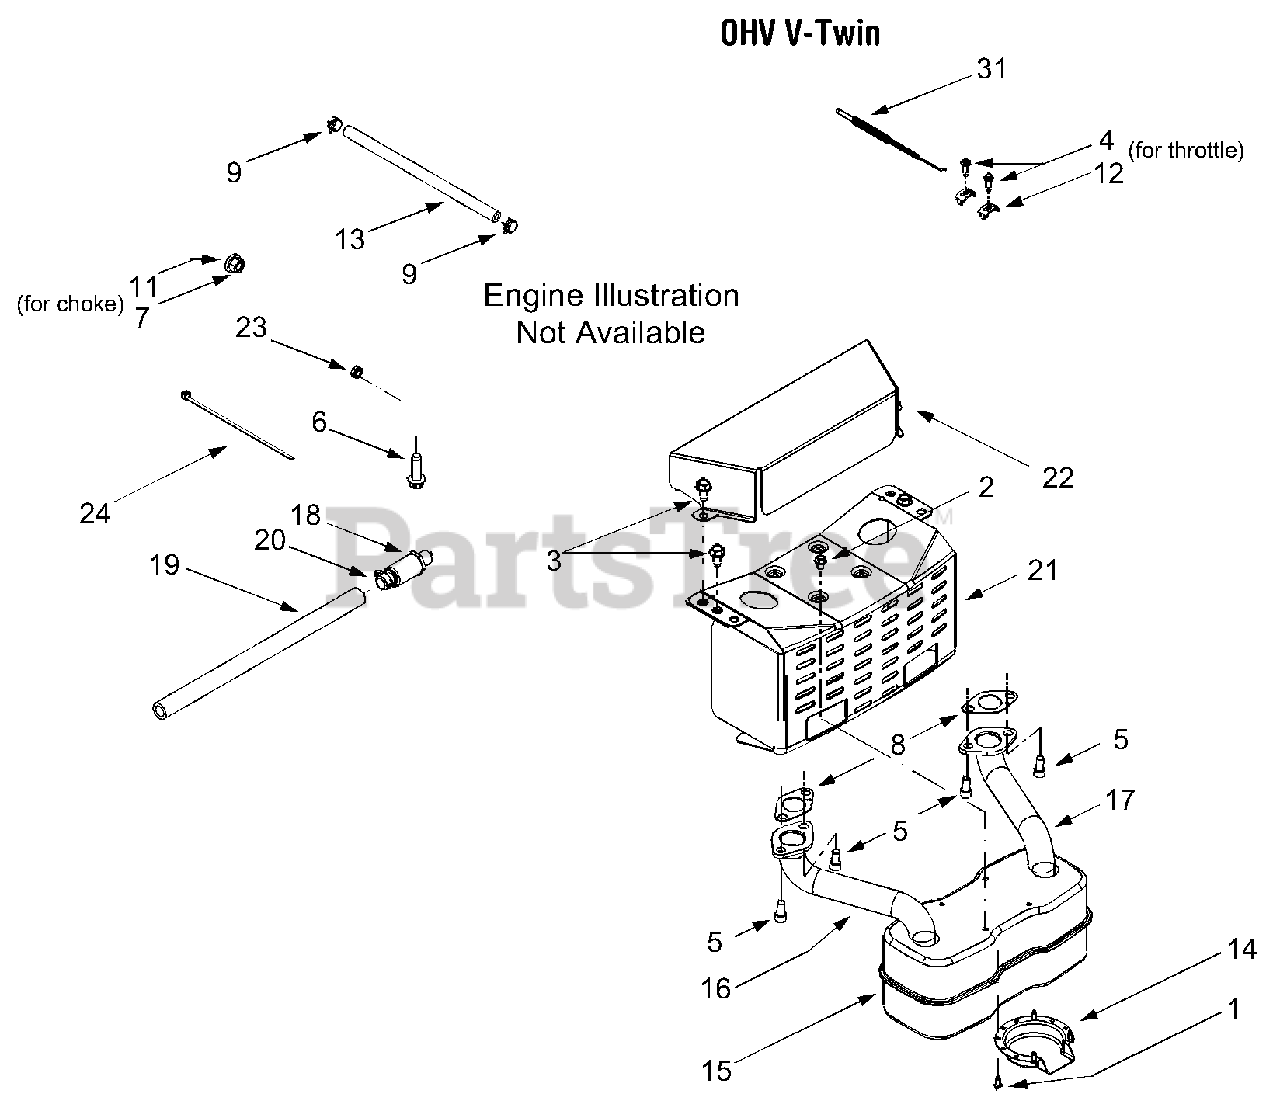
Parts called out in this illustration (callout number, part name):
1	Self-tapping Screw, #8-18 x .50
2	Self-tapping Screw, 1/4-20 x .50
3	Self-tapping Screw, 5/16-18 x .625
4	Screw, #10-32 x .625 (OHV V-Twin)
5	Socket Cap Screw, 5/16-18 x .625
6	Self-tapping Screw, 3/8-16 x 1.25
7	Hex Nut, 3/8-16
8	Exhaust Gasket (OHV V-Twin)
9	Hose Clamp
11	Lock Washer, .406 x .875 x .059
12	Casing Clamp (OHV V-Twin)
13	Fuel Line Hose
14	Muffler Deflector
15	Muffler, Twin Inlet (OHV V-Twin)
16	RH Exhaust Pipe (OHV V-Twin)
17	LH Exhaust Pipe (OHV V-Twin)
18	Oil Drain Valve
19	Oil Drain Hose
20	Oil Drain Cap
22	Engine Heat Shield (OHV V-Twin)
23	Hex Sems Nut, 1/4-20 (OHV V-Twin)
24	Cable Tie
31	Throttle Cable (OHV V-Twin)
